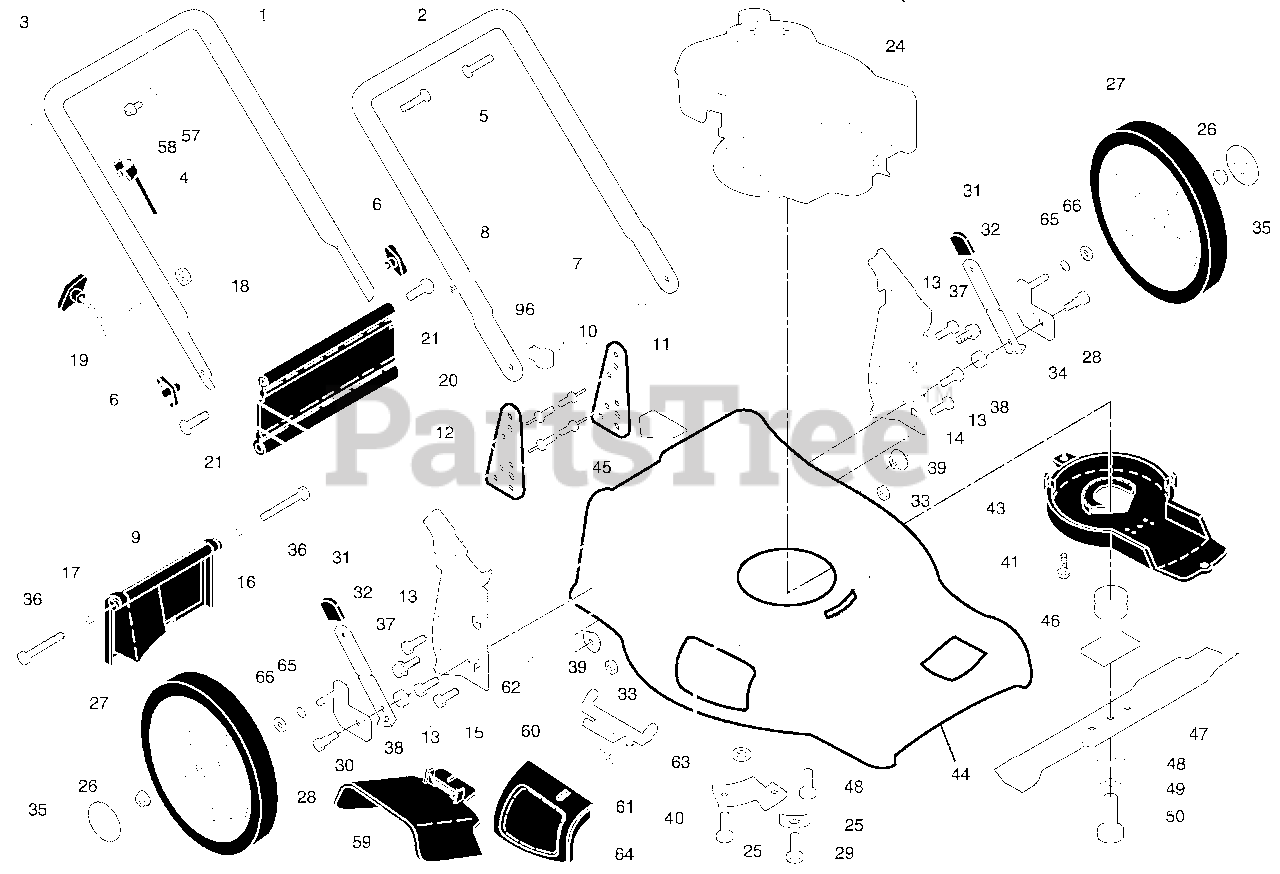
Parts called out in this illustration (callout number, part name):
1	Upper Handle
2	Lower Handle
3	Control Bar
4	Engine Zone Control Cable
5	Handle Bolt
6	Handle Knob
7	Hairpin Cotter
8	Wire Tie
9	Rear Door Assembly
10	Pop Rivet
11	Support Bracket, LH
12	Support Bracket, RH
13	Screw 1/4-20 x 5/8
14	Handle Bracket Assembly, LH
15	Handle Bracket Assembly, RH
16	Spring, Rear Door, LH
17	Spring, Rear Door, RH
18	Keps Locknut 1/4-20
19	Rope Guide
20	Rear Skirt
21	Hinge Screw 1/4-20 x 1-1/4
25	Screw, Hex Head, Threaded, Rolled 3/8-16 x 2
26	Nut, Hex, Flangelock 3/8-16
27	Wheel & Tire Assembly, Rear, 12"
28	Bolt, Shoulder 5/16-18
29	Washer, Special, Engine
30	Axle Arm Assembly, Rear, RH
31	Selector Knob
32	Selector Spring
33	Nut, Hex, Nylock 5/16-18
34	Axle Arm Assembly, Rear, LH
35	Hubcap
36	Bolt, Rear Door
37	Thread Cutting Screw w/Sems 5/16-18 x 3/4
38	Washer, Flat
39	Nut, Hex 3/8-16
40	Mounting Bracket, Debris Shield
41	Screw, Debris Shield
43	Debris Shield
44	Kit, Housing
45	Danger Decal
46	Blade Adapter / Pulley
47	Blade, 21"
48	Hardened Washer
49	Helical Washer 3/8
50	Blade Bolt, Hex Head, Grade 8
57	Bracket, Upstop
58	Screw
59	Discharge Deflector
60	Hinge Bracket
61	Spring
62	Rod, Hinge
63	Nut, Hex
64	Mulcher Door
65	O-Ring
66	Washer, Flat 1/2
96	Clip, Cable
96	Operator's Manual, English
96	Operator's Manual, French
96	Repair Parts Manual
